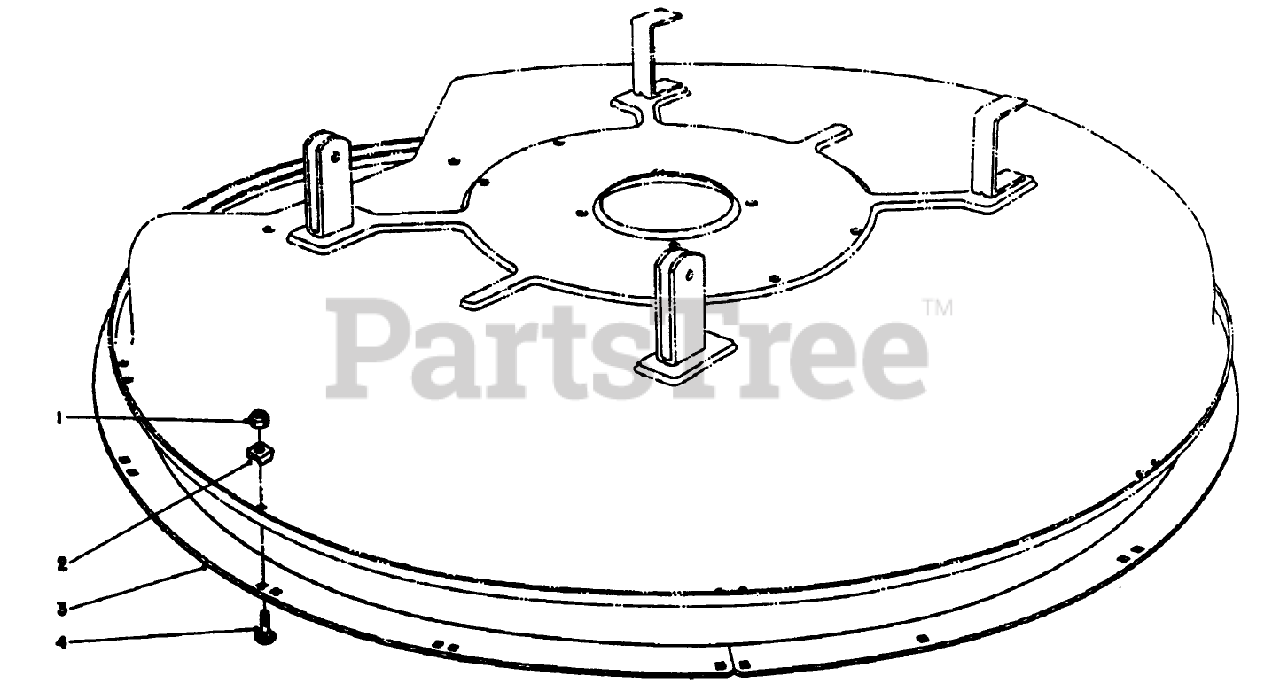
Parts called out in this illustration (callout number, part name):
1	NUT-LOCK, NI
3	DECK RING *B
4	BOLT-CARR
